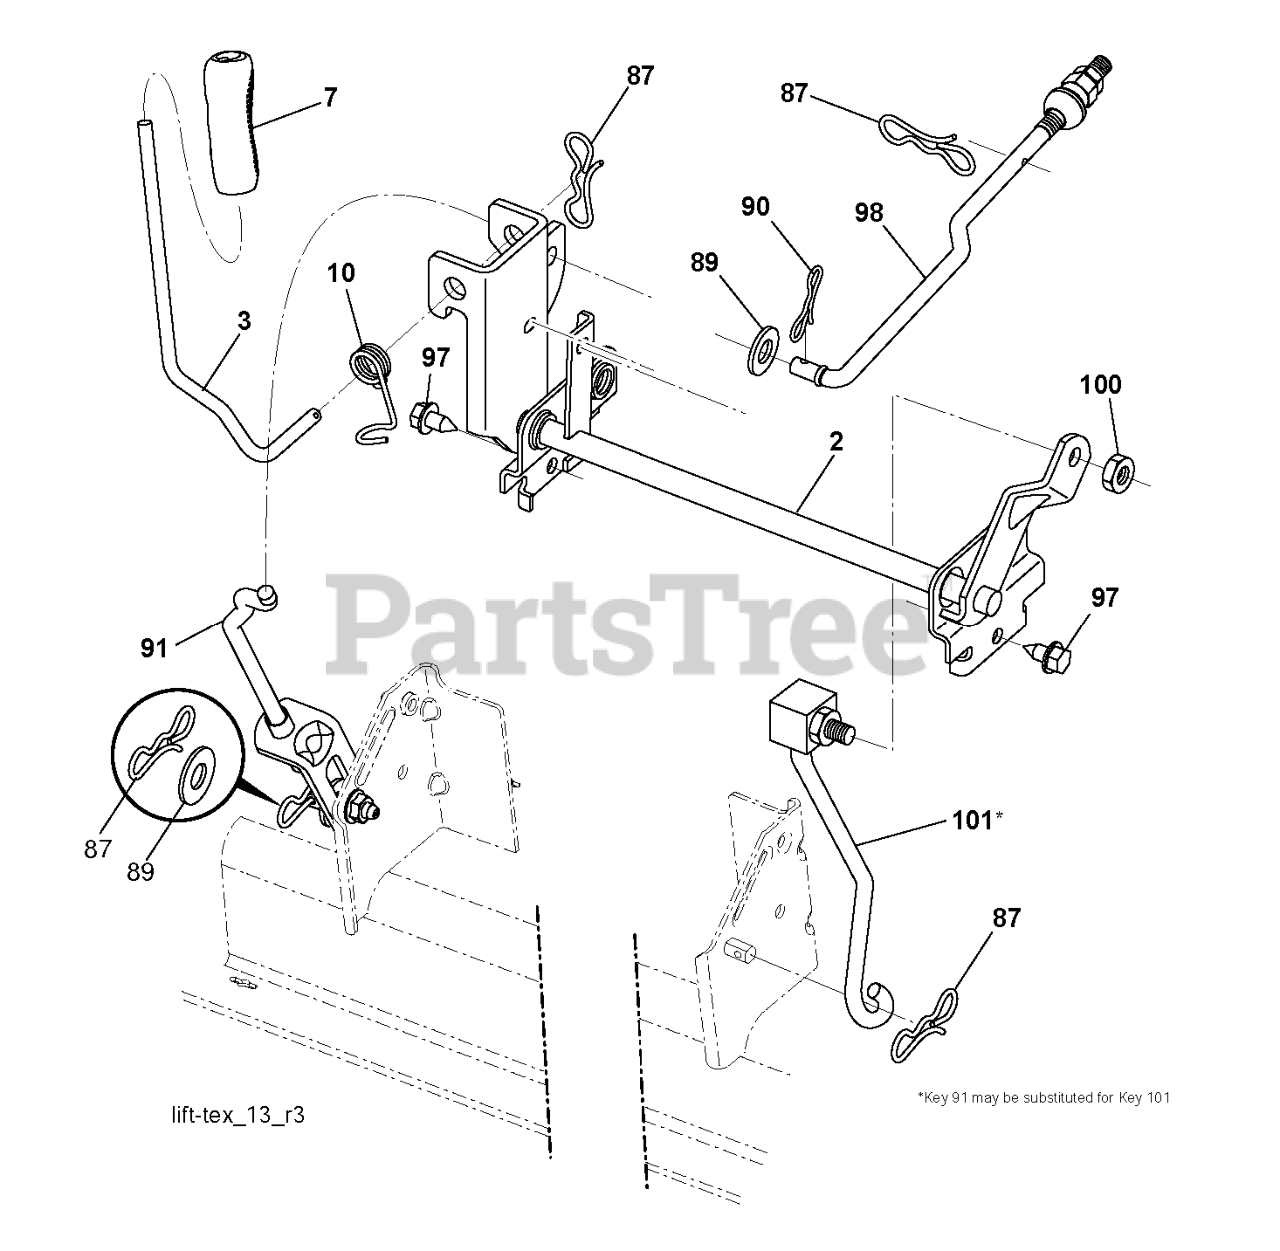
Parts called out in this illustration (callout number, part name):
2	SHAFT.ASM.LIFT.CROSS.H
3	LEVER.LIFT.HANDLE.GT
7	GRIP.HANDLE.LIFT.PVC.BLACK
10	SPRING.TORSION.LIFT.HANDLE
87	PIN.COTTER.7/16.BOW TI.
89	WASHER.CLEAR.ZINC
90	PIN.COTTER.5/16.BOW TI
91	LINK.ASM.LIFT.REAR
97	SCREW, 3/8-16X3/4
98	LINK.ASM.SUSP.FRONT.MW
100	LOCKNUT
101	LINK.ASM.LIFT.FIXE.38/42/46"
